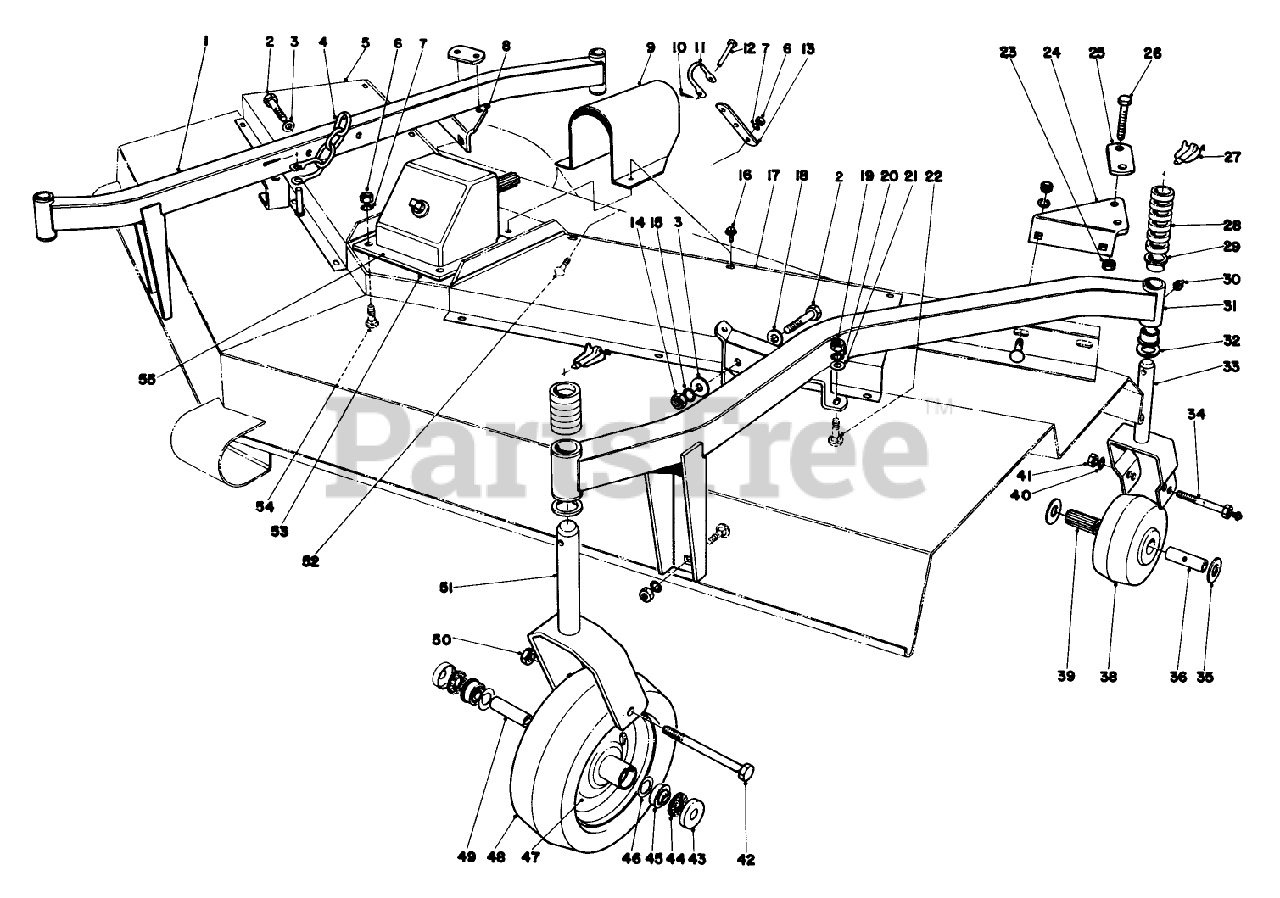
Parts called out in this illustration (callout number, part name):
1	Caster Arm R.H. (Incl. Ref. #29)
2	SCREW-HH
3	WASHER-FLAT
4	Lift Chain
5	RH DECK COVER R
6	NUT-HEX
7	WASHER-LOCK
8	Bracket-Clamp
9	Shroud Universal
10	PIN-COTTER
11	SHACKLE
12	PIN-CLEVIS
13	Lift Strap
14	NUT-HEX
15	WASHER-LOCK
16	SCREW-HHF
17	LH DECK COVER R
18	WASHER-FLAT
19	NUT-HH
20	WASHER-LOCK
21	WASHER-FLAT
22	SCREW-CARR
23	NUT-LOCK, NI
24	Bracket-Clamp
25	Bar-Caster Clamp
26	SCREW-HH
27	PIN-LYNCH
28	SPACER 1/2 IN
29	Bushing
30	FITTING-GREASE
31	Caster Arm L.H. (Incl. Ref. #29)
32	WASHER-THRUST
33	Caster Fork Rear
34	AXLE ASM
35	Bearing Retainer Seal
36	SPANNER BUSHING
38	WHEEL
39	ROLLER BRG W/46-8960
40	WASHER-LOCK/INT
41	NUT-JAM
42	Screw
43	AXLE SLINGER B
44	WASHER
45	.500 RF BALL BEARING
46	WASHER
47	Caster Wheel & Tire (Incl. Ref.# 48)
48	Tire
49	SPACER
50	NUT-HEX
51	Caster Fork
52	SCREW-CARR
53	SPACER R
54	SCREW-CARR
55	GEAR BOX ASM
